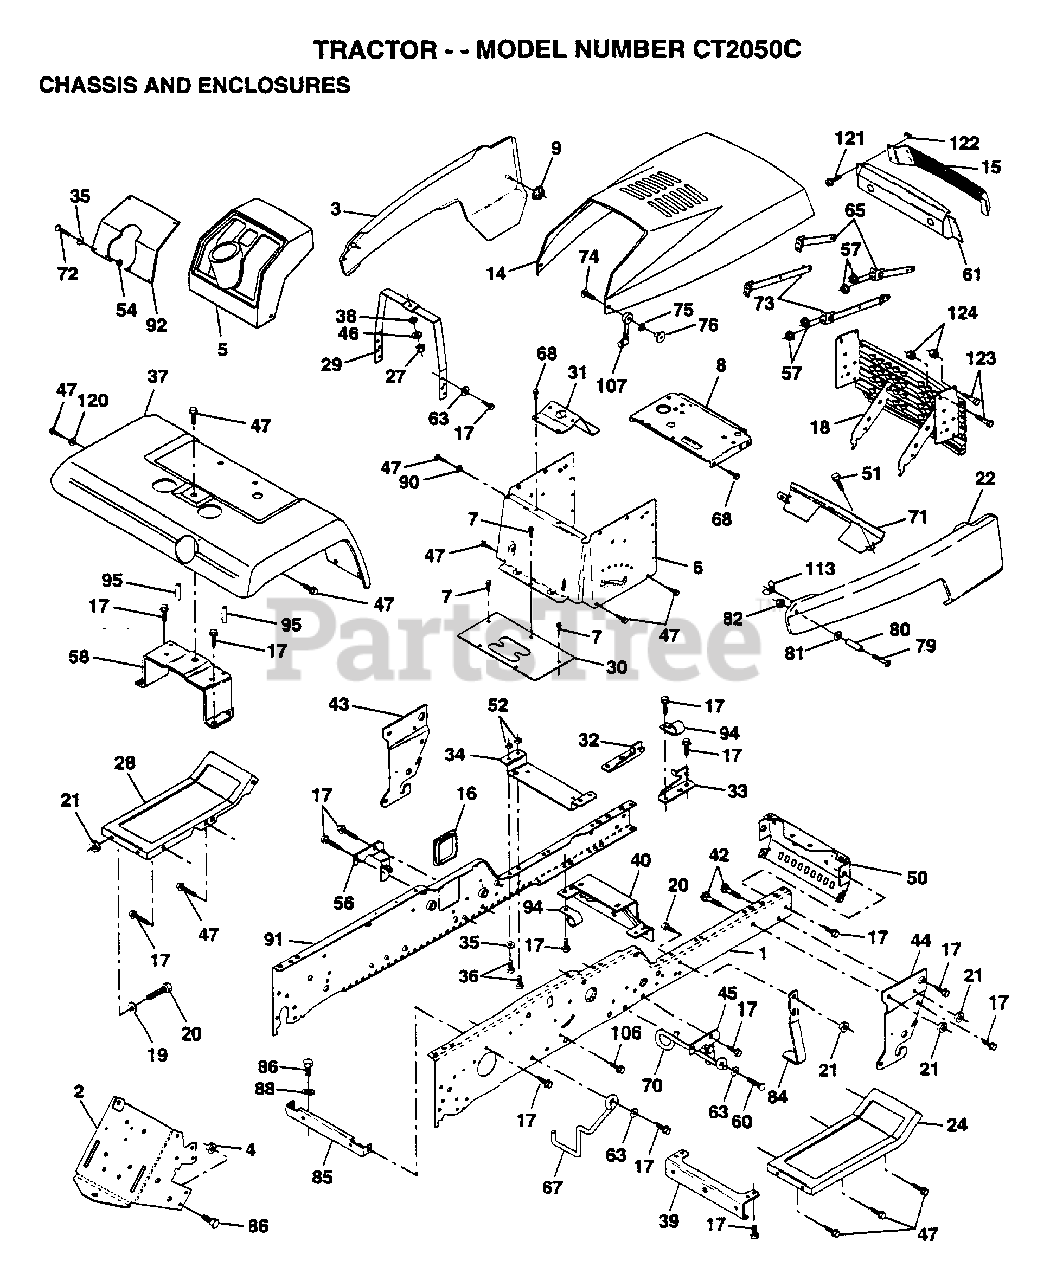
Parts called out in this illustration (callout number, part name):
2	DRAWBAR GT
3	PANEL.SD.LH.YT/GT
4	NUT.7/16
5	DASHBOARD BLACK
6	DASH.1PC.LOWER
7	SCREW
8	SUPPORT.DASH.BTRY
9	PAL NUT LT
15	LENS LT
16	COVER ACCESS
17	SCREW
19	WASHER
20	BOLT
22	PANEL.SD.RH.YT/GT
24	FOOTREST.RH.LT/GT
28	FOOTREST.LH.LT/GT
29	DASH.SUPT.YP/HUSQ
30	SADDLE.SCR.6SP
31	BRAKET.SUPT.STEER
32	BRACKET ASM FRAME
33	BRACKET ASM FRAME
34	BRACKET.ENG.SUPT.
35	WASHER
36	BOLT
37	FENDER.PNT.MS-550
38	LOCKWASHER
39	BRACKET.AXLE.FRT.
43	BRACKET.SUS.FT.LH
44	BRACKET.SUS.FT.RH
46	WASHER PM
47	SCREW LT
50	BRACKET.CHASSIS.
51	SCREW CRT
57	NUT
58	BRKT.ASM.FENDER
60	SCREW
63	WASHER
67	GUIDE BELT TRANS
68	SCREW LT
70	GUIDE.BELT.MID.SP
71	STRAP.PNT.GRILLE
72	SCREW
74	SCREW
75	LOCKWASHER
76	WELDNUT
79	SCREW
80	SPACER LT
81	WASHER
84	STOP.OVER.CENTER
85	BRACKET.SUPT.TRAN
86	BOLT
88	LOCKWASHER
90	LOCKWASHER
92	PLATE SLKSCR YP
94	CLIP GTV
95	NUT-PUSH YT
107	HOOD LATCH T
120	WASHER HYT
122	"""J"" FASTENER LT"
124	NUT
